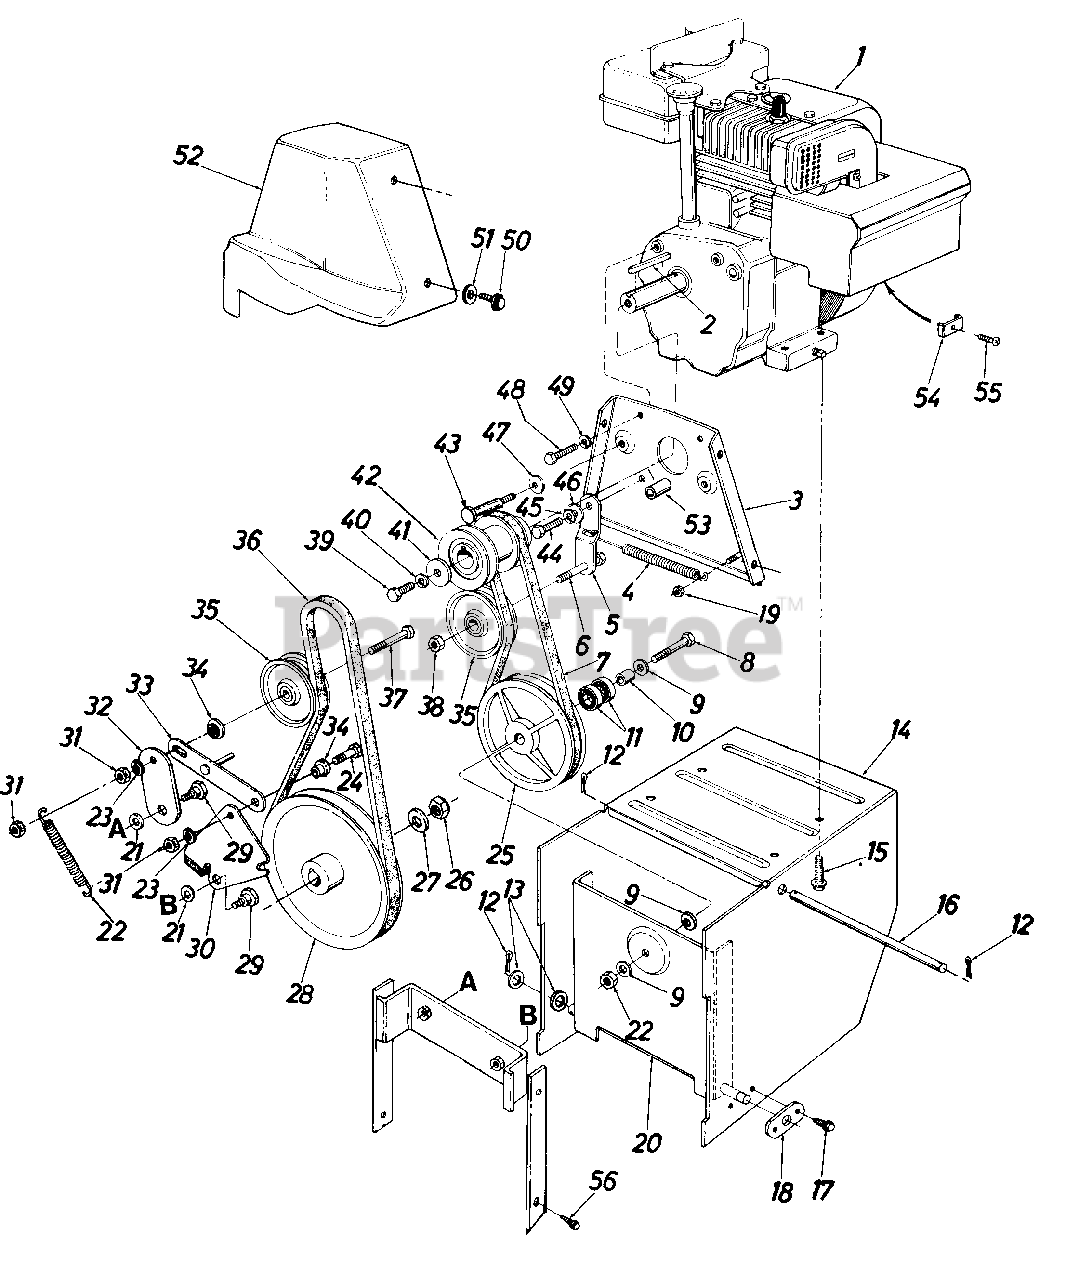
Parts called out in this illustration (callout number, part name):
1	Engine
2	Sq. Key 3/16" x 1.50" Lg.
3	Engine Plate Ass'y.
4	Extension Spring .50" O.D. x 3.97" Lg.
5	Drive Clutch Idler Brkt.
6	Hex Bolt 3/8-24 x 1.25" Lg.
7	"V"-Belt 3/8" x 29.0" Lg.
8	Hex Bolt 3/8-24 x 1.50" Lg.
9	Bell-Wash. .40" I.D. x .88" O.D. x .06
10	Spacer .38" I.D. x .62" O.D. x.75" Lg.
11	Ball Brg. .62" I.D. x 1.38" O.D. x .44
12	Cotter Pin 3/32" Dia. x .75" Lg.*
13	Fl-Wash. .53" I.D. x 1.00" O.D. x .125
14	Frame Ass'y.
15	Hex Wash. Hd. Self-Tap Scr. 3/8-16 x 1.25" Lg.
16	Shaft .50" Dia. x 9.50" Lg.
17	Hex Wash. Hd. Self-Tap Scr. 1/4-20 x .50" Lg.
18	Axle Bracket
19	Hex L-Nut 1/4-20 Thd.
20	Drive Pulley Support Brkt. Ass'y.
21	Bell-Wash. .40" I.D. x 1.13"O.D.
22	Extension Spring .50" O.D. x 3.97" Lg.
23	L-Wash. 3/8" I.D.
24	Hex Scr. 3/8-16 x 1.25" Lg.
25	6.00" O.D. Drive Pulley Ass'y
26	Hex Jam Cent. L-Nut 5/8-18 Thd.
27	Fl-Wash. .64" I.D. x .94" O.D. x .06
28	1/2" V-Pulley .625" I.D. x 7.50" O.D.
29	Shld. Bolt .625" Dia. x .170" Lg. (3/8-16)
30	Brake Bracket Ass'y.
31	Hex Ins. L-Nut 3/8-16 Thd.
32	Auger Clutch Idler Brkt.
33	Brake Linkage Ass'y.
34	Shld. Spacer.625" I.D.
35	Flat Idler 2.25" O.D.
36	"V"-Belt 3/8" x 38" Lg.
37	Hex Bolt 3/8-16 x 2.25" Lg.
38	Hex Ins. Jam L-Nut 3/8-24 Thd.
39	Hex Bolt 3/8-24 x 1.50" Lg.
40	L-Wash. 3/8" I.D.
41	Fl-Wash. .40" I.D. x 1.25" O.D.
42	Double Groove Engine Pulley
43	Shld. Scr. .498" x 3.0" Lg.
44	Hex Bolt 5/16-24 x 1.00" Lg.
45	L-Wash. 5/16" I.D.*
46	Shld. Spacer.320" I.D.
47	Bell-Wash. .40" I.D. x .88" x .06
48	Hex Bolt 5/16-24 x .62" Lg.
49	L-Wash. 5/16" I.D.
50	Hex Wash. Hd. Self-Tap Scr. 1/4-20 x .50" Lg.
51	Fl-Wash. .28" I.D. x .75" O.D. x .06
52	Belt Cover
53	Spacer
54	Throttle Control Wire Clamp
55	Hex Sems Scr. #10-32 x .62" Lg.
56	Hex Wash. Hd. Self-Tap Scr. 3/8-16 x .75" Lg.
